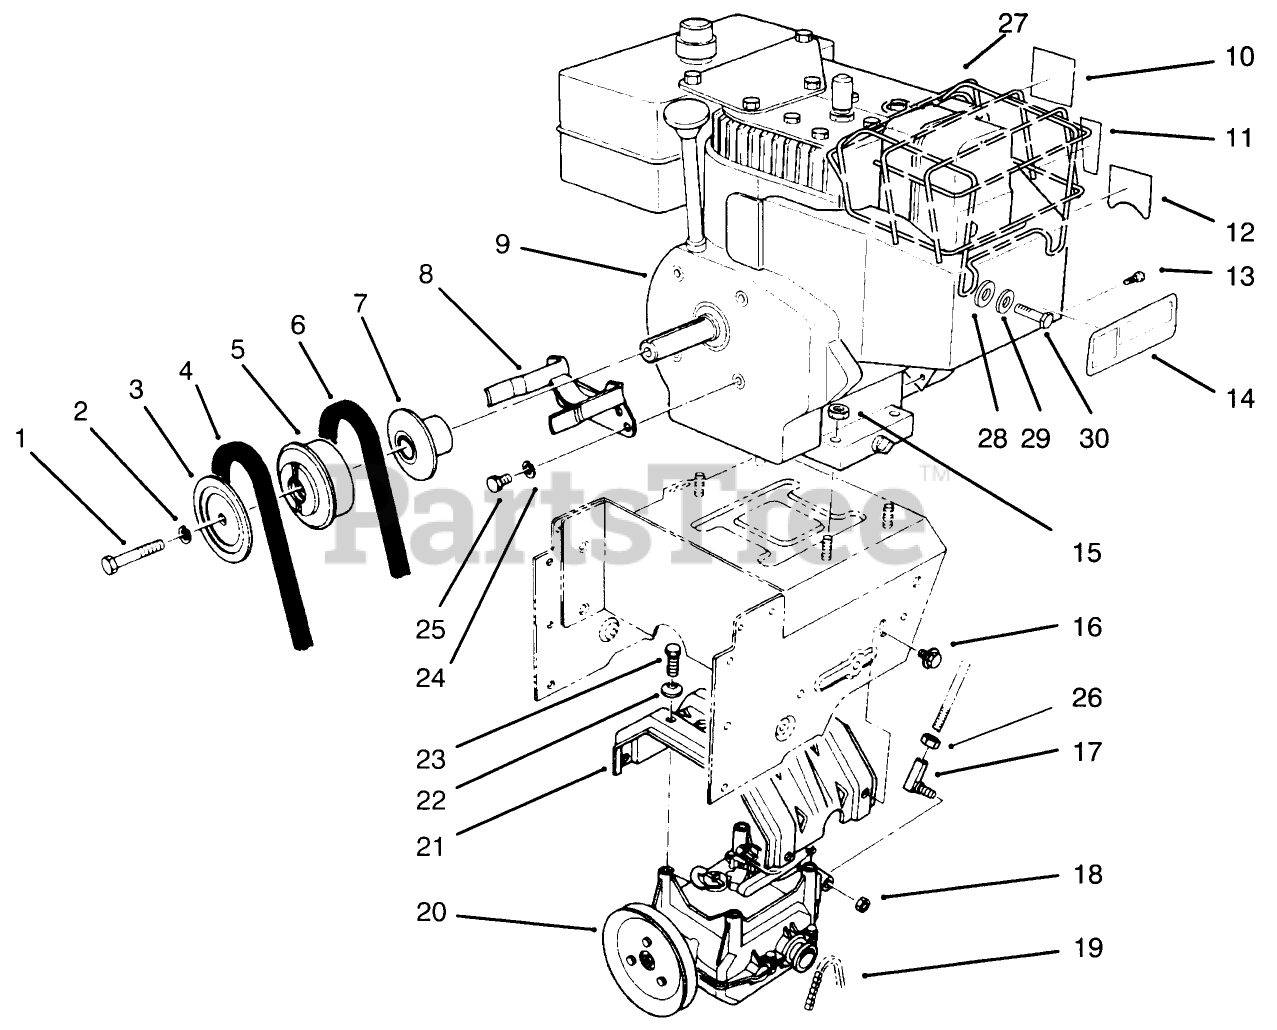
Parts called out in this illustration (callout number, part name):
1	SCREW-HH
2	WASHER-LOCK
3	SHEAVE-HALF, IMPELLER
4	V-BELT
5	PULLEY-ENGINE, CENTER
6	V-BELT-TRACTION
7	SHEAVE-HALF, TRACTION
8	Guide-Belt
9	Engine
10	DECAL - PRIMER
11	DECAL-THROTTLE
12	DECAL-CHOKE
13	SCREW-HWH
14	DECAL-WARNING, HOT SURFACE
14	DECAL - HOT SURFACE
15	NUT-HF
16	SCREW-HHF
17	JOINT-BALL
18	NUT-LOCK, NI
19	CHAIN
20	TRACTION GEARCASE ASM
21	Frame-Transmission
22	WASHER-SPRING
23	SCREW-HWHTF
24	WASHER-LOCK
25	SCREW-HH
26	NUT-HJ
27	Guard-Muffler
28	Washer-Flat
29	Washer-Lock
30	SCREW (only on: 38053)
